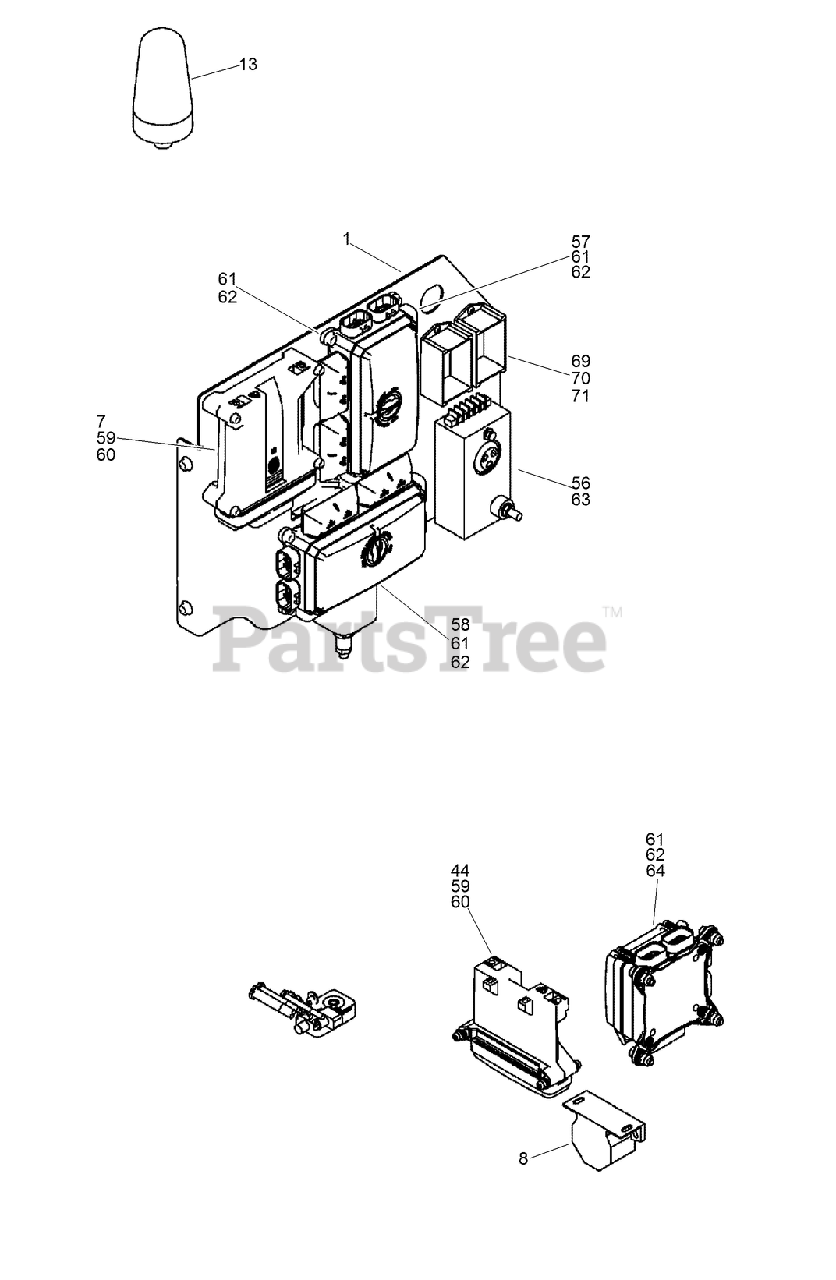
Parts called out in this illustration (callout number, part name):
1	PLATE - Mounting, Electrical
7	CONTROLLER - Programmed Module B (Electrical Box Area)
8	ALARM-BACKUP
13	ASSEMBLY - Strobe, Small
44	CONTROLLER - Programmed
57	BOX-VEC, MAIN (B)
58	BOX-VEC, MAIN (A)
59	SCREW-FLANGE, METRIC
60	NUT, METRIC FLANGE PREVAILING - M6 Zinc
61	SCREW-HH
62	NUT-TORQUE, PREVAILING
63	NUT-HEX
69	CONNECTOR-PACK, RESISTOR
70	SCREW - PHd Type 1 #10-24 x 5/8 CST ZND
71	NUT-#10-24 KEPS
